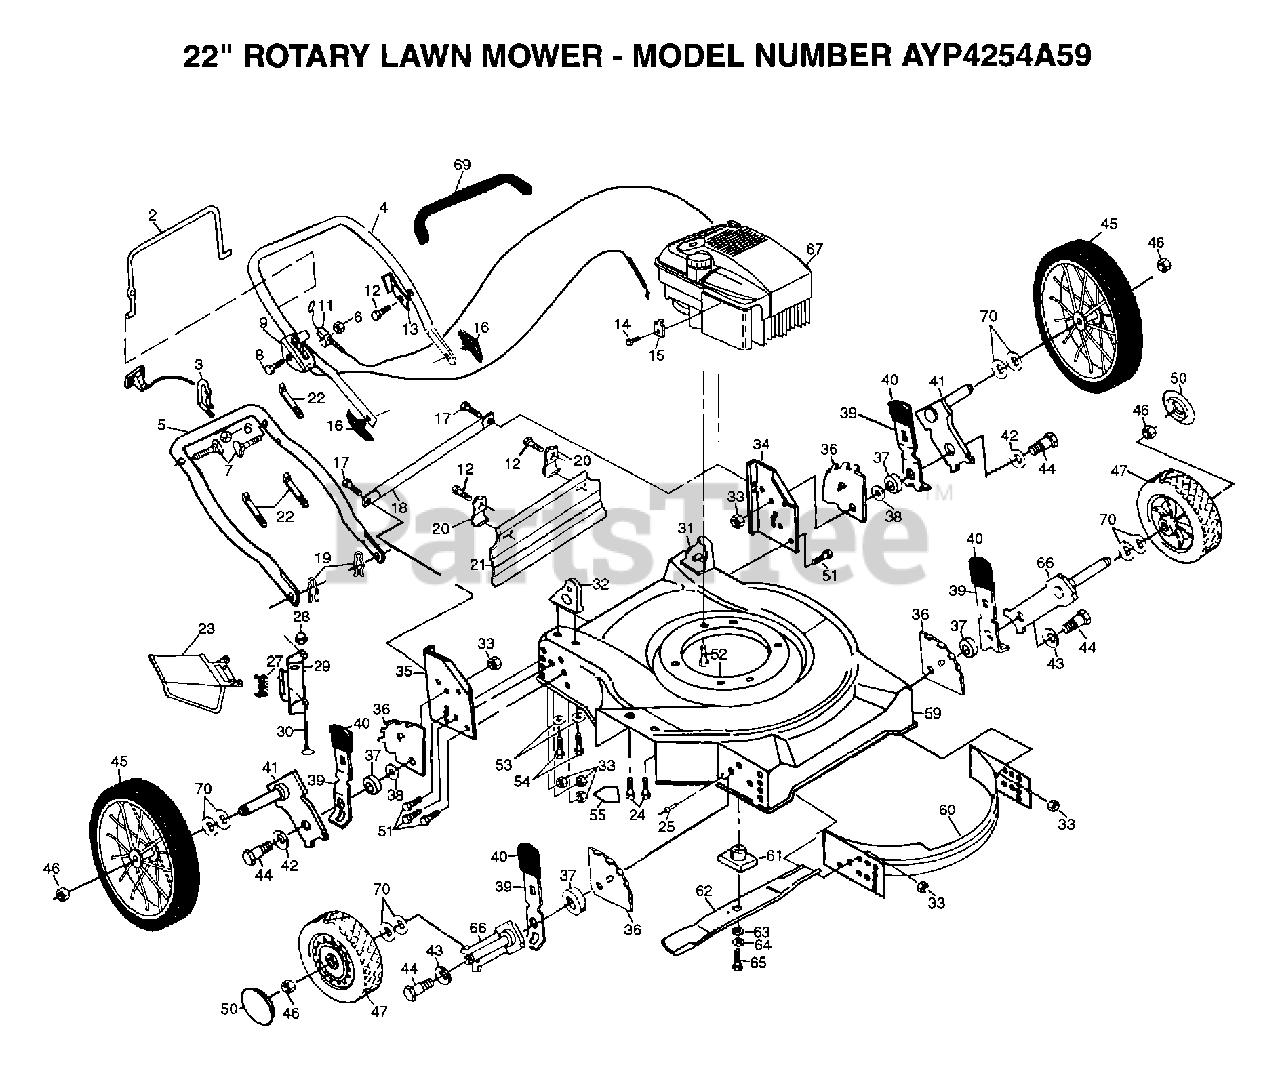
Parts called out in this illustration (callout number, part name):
2	CONTROL BAR PM
3	ROPER GUIDE PM
7	BOLT.HANDLE.LM
8	SCREW.HXHD.WASH.
9	"CONTROL, THROTTLE"
11	"CABLE,ENG ZONE CO"
12	TAPPING SCREW
13	"BRKT,UPSTOP"
14	SCREW PM
15	CABLE CLAMP
16	KNOB HANDLE
17	SCREW
18	ROD.SUPPORT.WB.
19	HAIRPIN COTTER
20	"BRKT,DEFL PM"
21	SKIRT.REAR.22SD.
24	SCREW
25	BLIND RIVET
27	"SPRING,TORSION"
28	PUSH ON SPEED NUT
29	"BRKT,HSG"
30	"ROD,HINGE "
33	LOCKNUT PM
34	BRACKET.SUPT.WHEL
35	BRACKET.SUPT.WHEL
36	BRACKET.ADJ.9POS.
38	WASHER PM
39	SPRING SELECTOR
40	KNOB PM
41	AXLE ARM ASSY R
43	"WASHER, BELLEVIL."
44	BOLT SHLD 3/8-16
45	WHEEL & TIRE PM
46	HEX FLANGE LOCKNT
47	WHEEL & TIRE PM
50	HUB CAP
52	SCREW
53	STEEL WASHER
54	SCREW
55	DECAL-DANGER PM
59	KIT.HSG.22SD.PUSH
60	BAFFLE.FRT/REAR
61	BLADE ADAPTOR
62	"BLADE.MULCH.22"""
63	"WASHER,HARDEN"
64	LOCKWASHER
65	SCREW
66	AXLE ARM AS PM
70	WAVE WASHER
